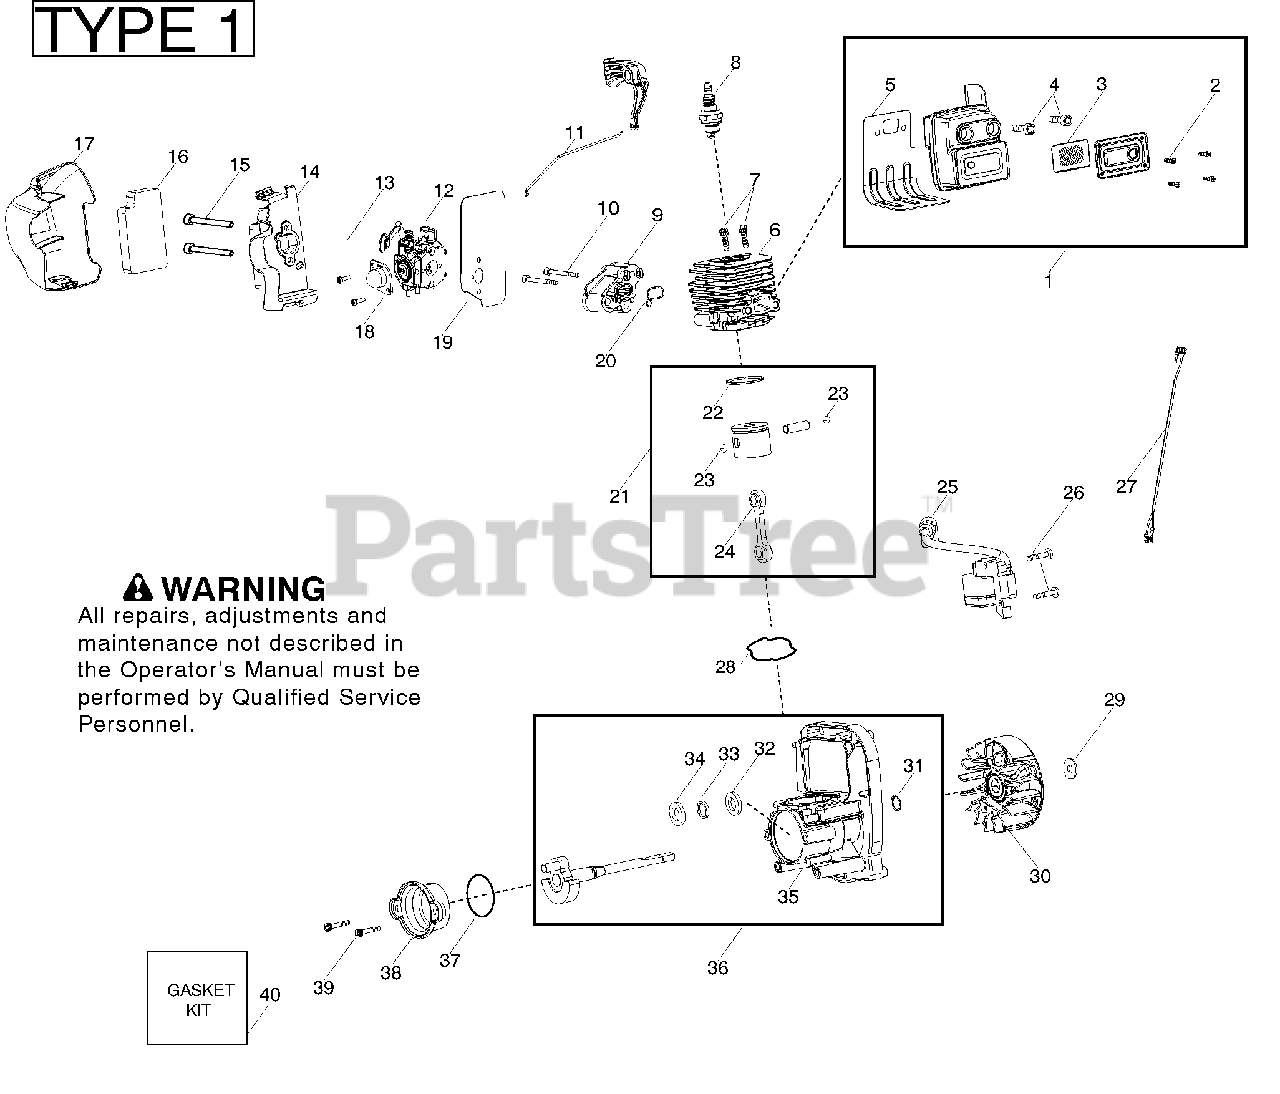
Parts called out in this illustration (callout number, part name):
1	Assy - Muffler
3	Kit - Spark Screen
5	Gasket-Muffler (gasket kit)
6	Cylinder
8	Spark Plug (RCJ-6Y)
9	Adapter - Carb.
11	Linkage - Throttle
12	Kit - Carb. Assy (C1U - W45)
13	Lever- Choke (Yellow)
14	Base - Airbox
17	Cover - Air Box Filter
18	Bulb - Purge (walbro 188-16)
19	Gasket (Carb / Adapter) (gasket kit)
20	O-Ring (Adapter / Cylinder) (gasket kit)
21	Kit - Piston / Connecting Rod
22	Ring - Piston
23	Retainer - Wrist Pin
24	Kit - Assy. Connecting Rod
25	Module - Ignition
27	Assy - Wire Harness
28	O-Ring (Cyl./Crankcase) (gasket kit)
30	Assy - Flywheel
31	Retainer - Crankshaft
32	Bearing - Outer
34	Bearing - Inner
35	Assy - Crankcase
36	Assy - Crankcase & Crankshaft
37	O-Ring (Rear Plug) (gasket kit)
38	Assy - Rear Plug
40	Kit - Gasket
